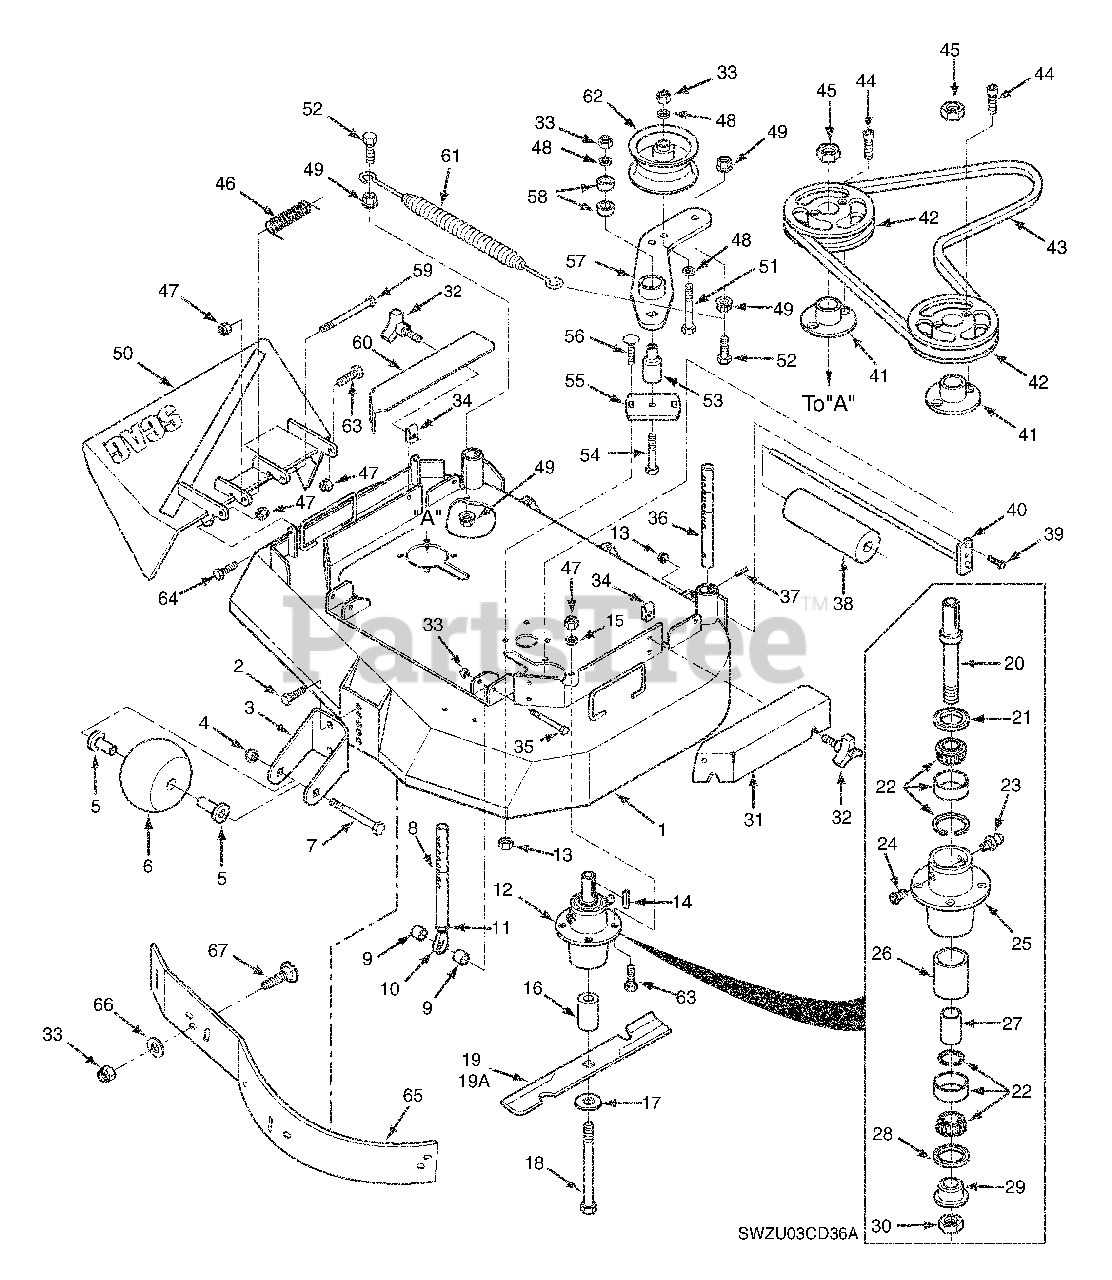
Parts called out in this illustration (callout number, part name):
1	Cutter Deck
2	Capscrew, 3/8-16 x 1.0" Serrated Flange Hex Hd
3	Bracket, Anti-Scalp Wheel
4	Lock Nut, 3/8-16 Center Lock
5	Bushing, .376" ID Oilite
6	Wheel, Anti-Scalp
7	Bolt, Carriage 3/8-16 x 4"
8	Pin Assy., Deck Adj.
9	Spacer, Deck Adjustment Pin
10	Rod End, Male 3/8-24 RH Thread
11	Nut, 3/8-24 Jam
12	Spindle Assembly
13	Nut, 5/16-18 Serrated Flange
14	Key,1/4" x 1/4" x 2"
15	Lock Washer 5/16"
16	Spacer, Spindle
17	Flatwasher, 5/8 W
18	Bolt, Hex Head 5/8-11 x 9-1/2"
19	Cutter Blade, 18"
19A	Cutter Blade, 18" Hi Lift
20	Spindle Shaft
21	Seal, Cutter Spindle Top
22	Tapered Bearing Set (Two Bearings W/Race)
23	Grease Fitting
24	Relief Fitting, Cutter Spindle
25	Spindle Housing
26	Spacer, Outside
27	Spacer, Inside
28	Seal, Cutter Spindle Bottom
29	Spindle Bushing
30	Nut, Spindle
31	Belt Cover, LH
32	Wing Nut, 3/8-16
33	Nut, 3/8-16 Elastic Stop
34	U-Nut, 3/8-16
35	Bolt, Hex Head 3/8-16 x 2-1/2"
36	Pin, Deck Adj. Rear
37	Pin, Sloted Spring 3/16 x 1-1/2"
38	Guide, Roller
39	Bolt, Hex Head 5/16-18 x 1"
40	Roller Shaft
41	Tapered Hub
42	Pulley
43	Belt, Cutter Deck
44	Capscrew, Socket Head. 1/4-20 x 1-3/8"
45	Hex Nut, 5/8-11
46	Spring, Chute Return
47	Hex Nut, 5/16-18 Elastic Stop
48	Flatwasher, 3/8" (.938 x .391 x .105)
49	Nut, 3/8-16 Serrated Flange
50	Discharge Chute
51	Capscrew, Hex Head 3/8-16 x 3-3/4"
52	Capscrew, Hex Head 3/8-16 x 1-1/2"
53	Pivot, Idler - Long
54	Capscrew, Hex Head 38/16 x 3-1/4"
55	Base, Idler Pivot
56	Bolt, Carriage 5/16-18 x 1"
57	Idler Arm Weldment
58	Ball Bearing
59	Bolt, Hex Head 5/16-18 x 4-1/4"
60	Belt Cover, RH
61	Spring, Deck Idler
62	Pulley, Idler
63	Bolt, Hex Head 5/16-18 x 1-1/2"
64	Bolt, Hex Head 5/16-18 x 1-3/4"
65	Baffle Weldment
66	Flatwasher, 3/8" (.391 x .938 x .105)
67	Bolt, Carriage 3/8-16 x 1"
